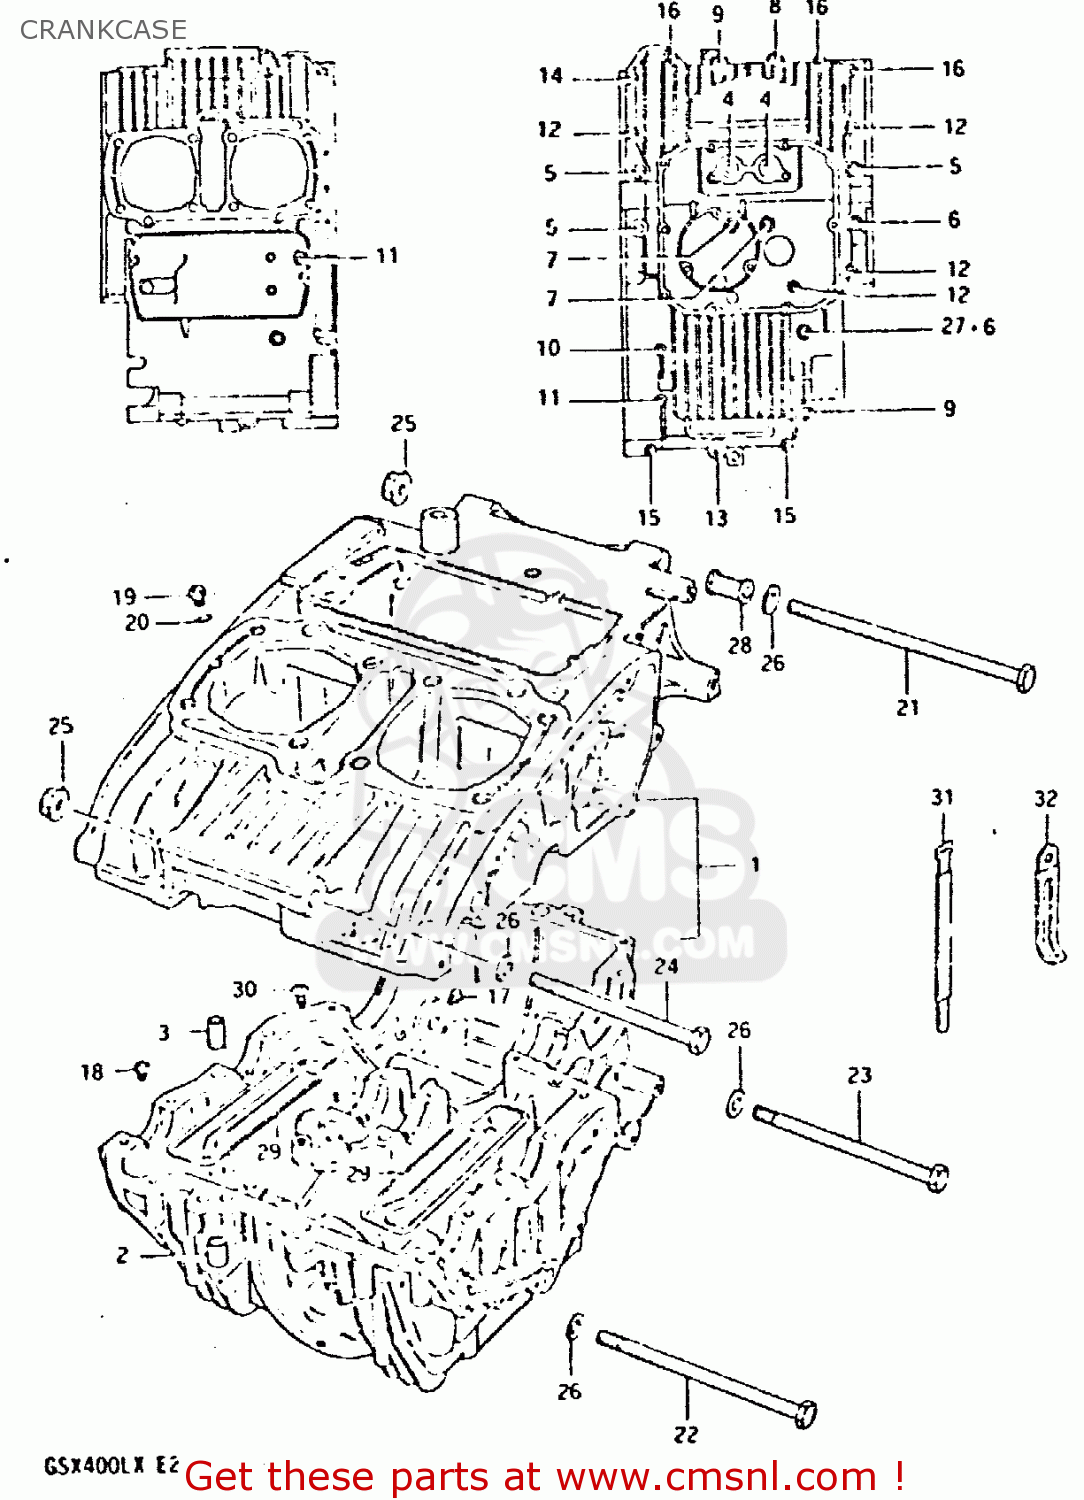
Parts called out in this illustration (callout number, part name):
1	CRANKCASE SET
2	PIN(10.4X13X22)
3	PIN (11X20)(SUS)
4	BOLT
5	BOLT
6	BOLT
7	BOLT
8	BOLT 8X65
9	BOLT (8X45)
10	BOLT
11	BOLT
12	BOLT (6X90)
13	BOLT (6X70)
14	BOLT 6X65
15	BOLT ,6X50
16	BOLT,UNDER
17	JET
18	JET
19	JET
20	O-RING
21	BOLT 10X250
22	BOLT(10X210)
23	BOLT 10X160
24	BOLT
25	NUT 10MM
26	WASHER
27	GASKET 8.2X14X1 (NAS)
28	SPACER,ENGINE MOUNT
29	PLATE,OIL SEPARATOR
30	SCREW
31	CLAMP
